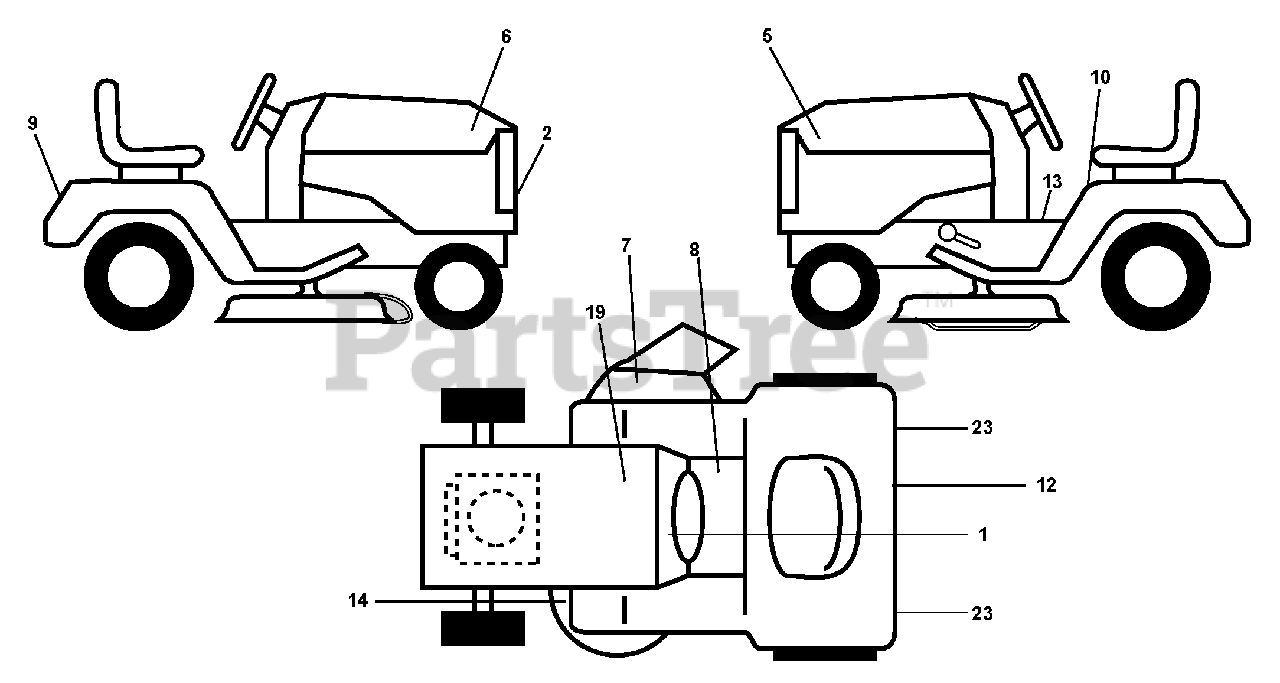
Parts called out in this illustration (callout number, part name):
1	Decal, Operating Instruction
2	Decal, Grille Husqvarna
5	Decal, Inst Hood LH GTH220 Hydro
6	Decal, Insrt Hood RH GTH220 Hydro
7	Decal, Warning Multi-Language
8	Decal, Brake Parking Saddle
9	Decal, Fender
10	Decal, Caution
11	Decal, Clutch/Brake
12	Decal, D-Bar Ctrl. Mvt Hyd YT/GT
13	Decal, Sdl Cold Start Hyd E/F
14	Decal, V-Belt Schematic
19	Decal, Battery
23	Reflector, Taillight
